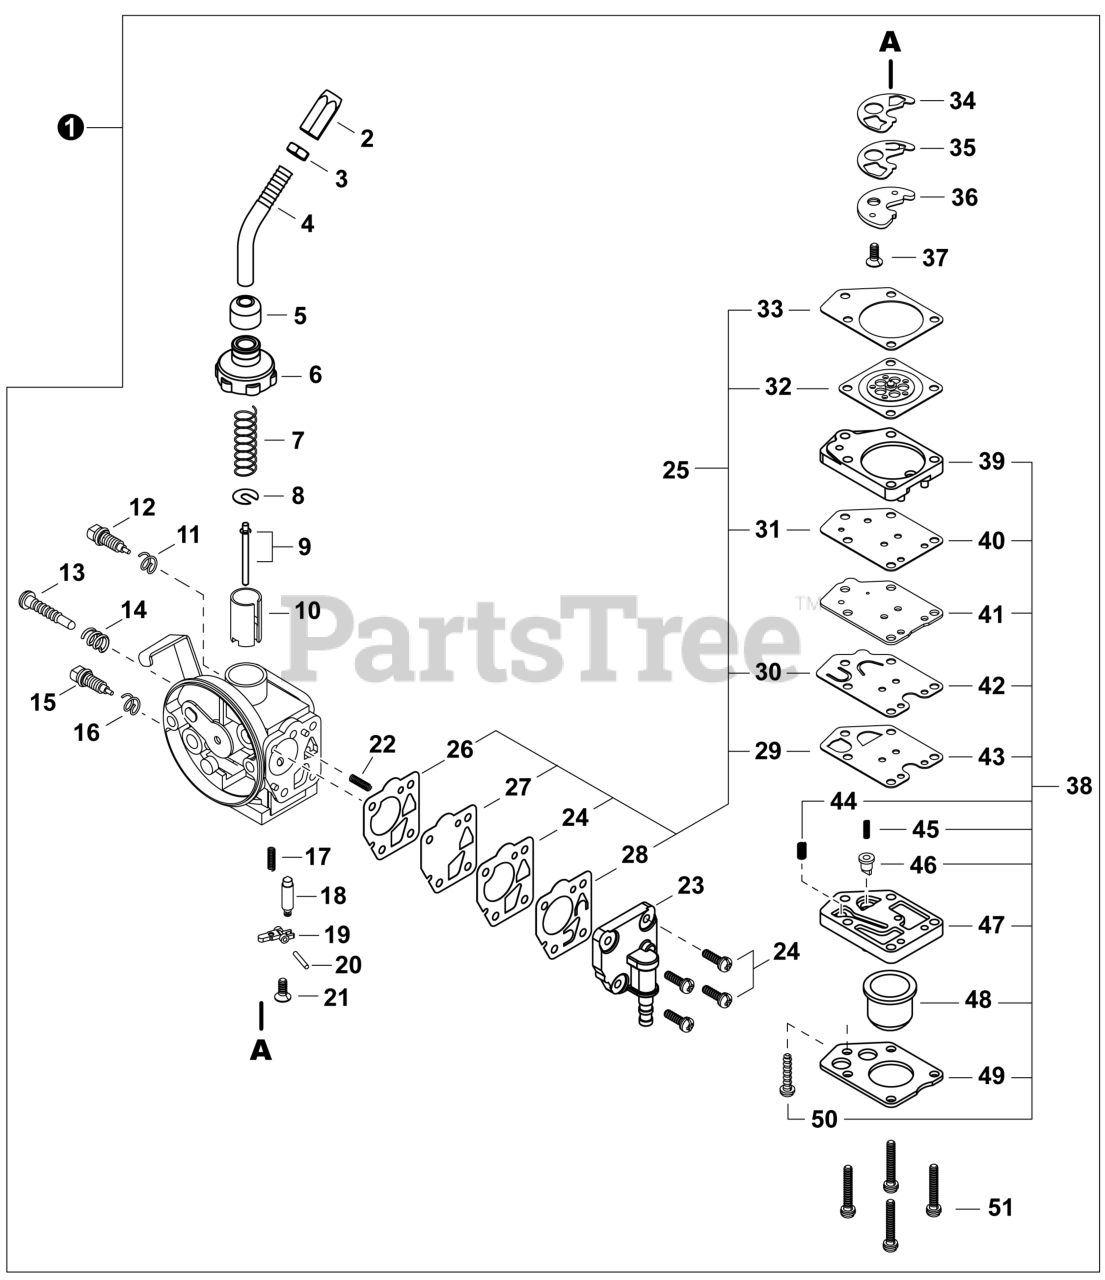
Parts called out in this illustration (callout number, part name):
1	CARBURETOR DPV11W-18J
2	ADJUSTER, CABLE
3	NUT, LOCK
4	PIPE, CABLE ADJUSTER
5	CAP, DUST
6	CAP, CARBURETOR
7	SPRING, THROTTLE
8	WASHER, SPRING SUPPORT
9	NEEDLE, JET
10	VALVE, SLIDE
12	SCREW, SLOW AIR
13	SCREW, IDLE ADJUST
15	SCREW, MAIN ADJUST
18	VALVE, INLET NEEDLE
19	LEVER, INLET CONTROL
20	PIN, METERING LEVER
21	SCREW M3x8
23	PUMP BODY
25	GASKET / DIAPHRAGM KIT
26	GASKET, DIAPHRAGM
27	DIAPHRAGM, METERING
28	VALVE, PUMP
30	VALVE, CHECK
32	DIAPHRAGM, METERING
33	GASKET, METERING DIAPHRAGM
35	VALVE, CHECK
37	SCREW M3x8
38	PURGE PUMP KIT
39	COVER, PUMP
41	PLATE, PUMP
42	VALVE, CHECK
46	VALVE, CHECK
47	BODY, PURGE
48	BULB, PURGE
49	RETAINER, PURGE BULB
51	SCREW 3x20
